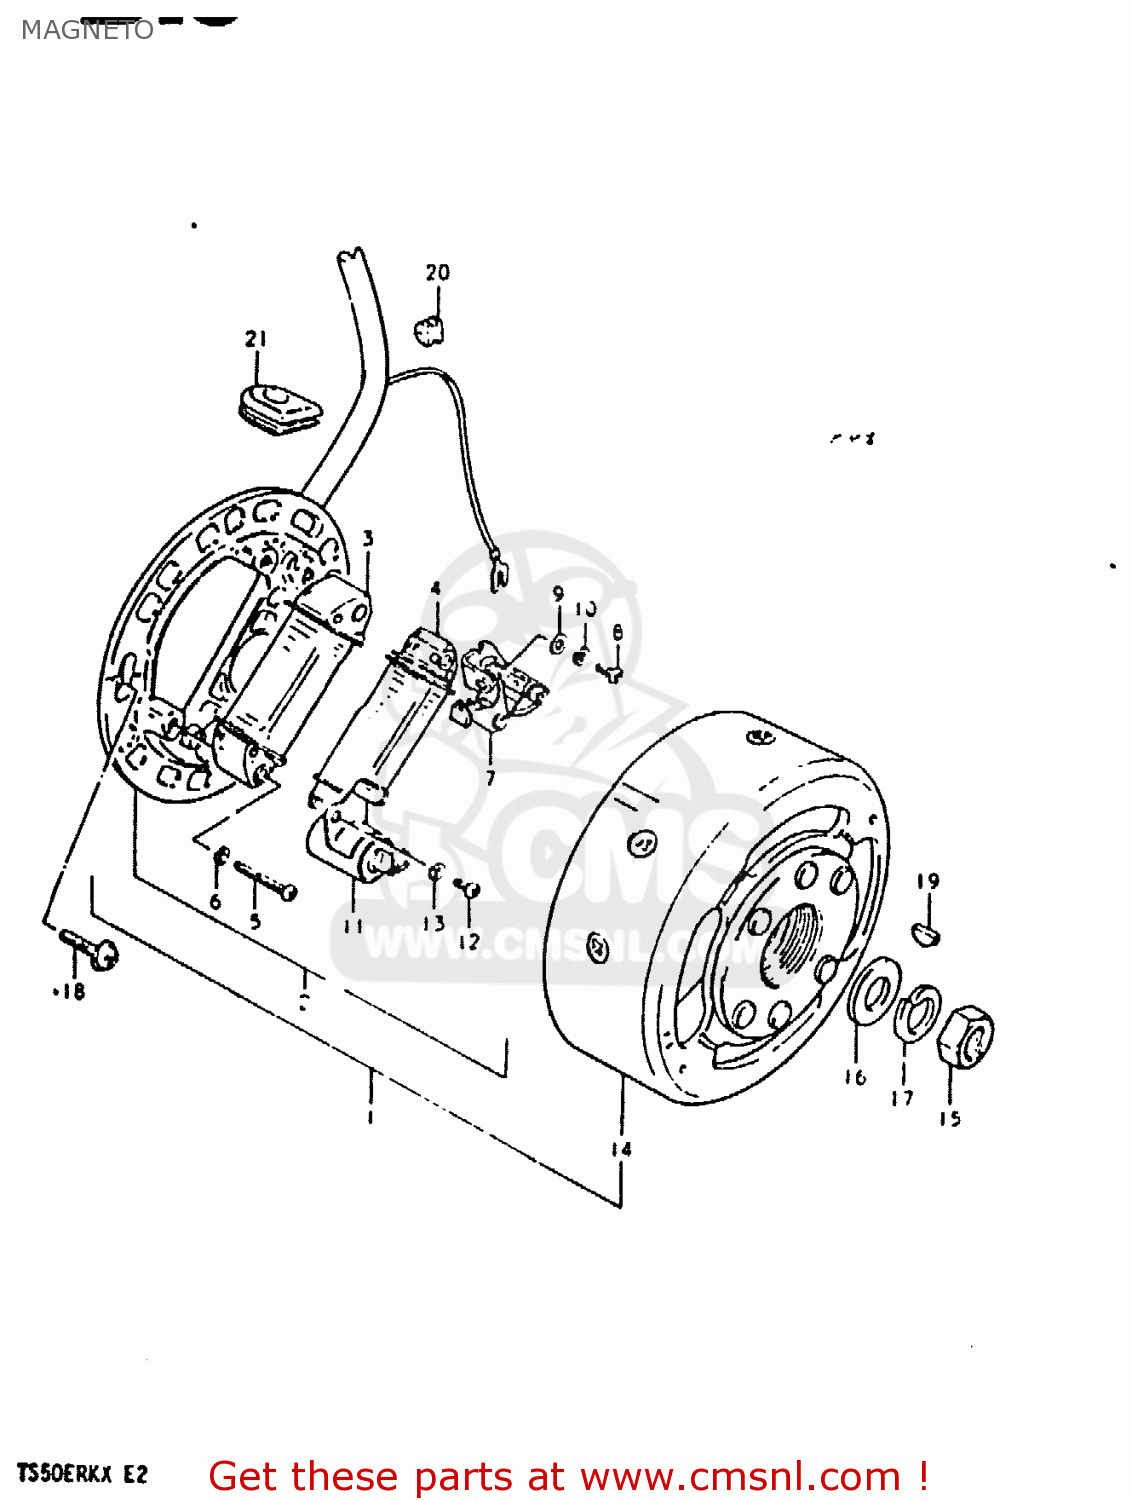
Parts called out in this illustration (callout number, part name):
1	MAGNETO ASSY
2	STATOR ASSY
3	COIL, LIGHTING
4	COIL,PRIMARY
5	SCREW (4X30)
6	LOCK WASHER
7	POINT ASSY,CONTACT
8	SCREW(4X10)
9	WASHER
10	LOCK WASHER
11	CONDENSER
12	SCREW
13	LOCK WASHER
14	ROTOR ASSY
15	NUT (10MM)
16	WASHER
17	LOCK WASHER
18	SCREW(5X14)
19	KEY
20	GROMMET,NEUTRAL LEAD WIRE
21	GROMMET
